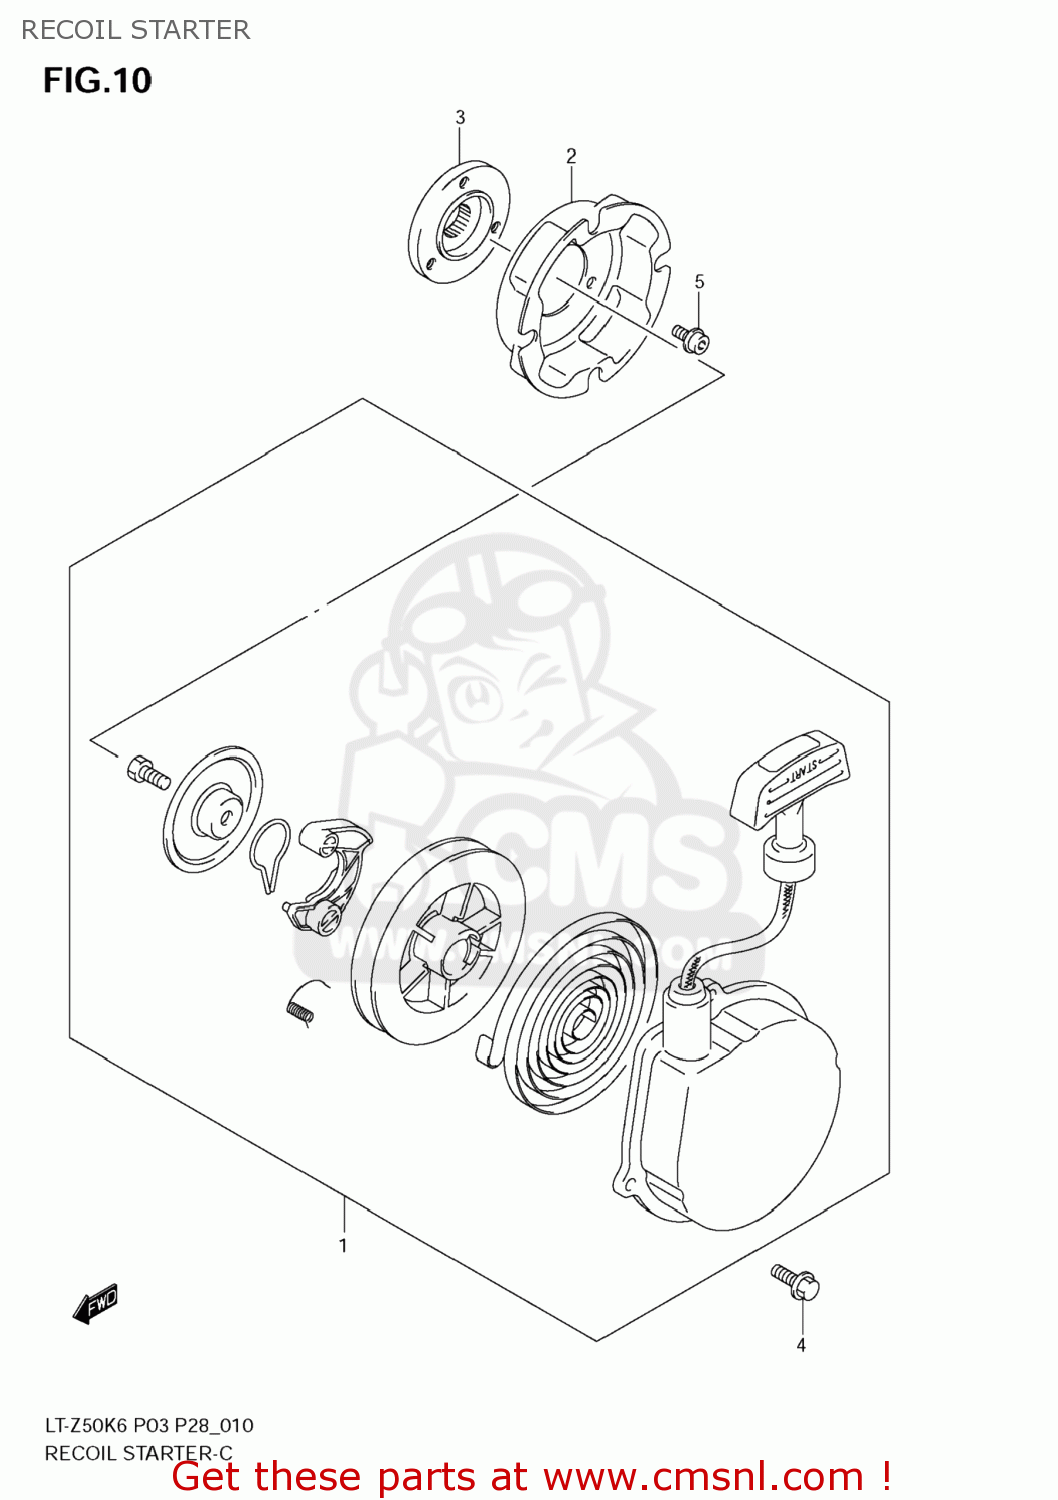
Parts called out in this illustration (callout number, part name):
1	STARTER ASSY.RE
2	CUP,STARTER
3	SPACER,STARTER CUP
4	BOLT
5	BOLT
